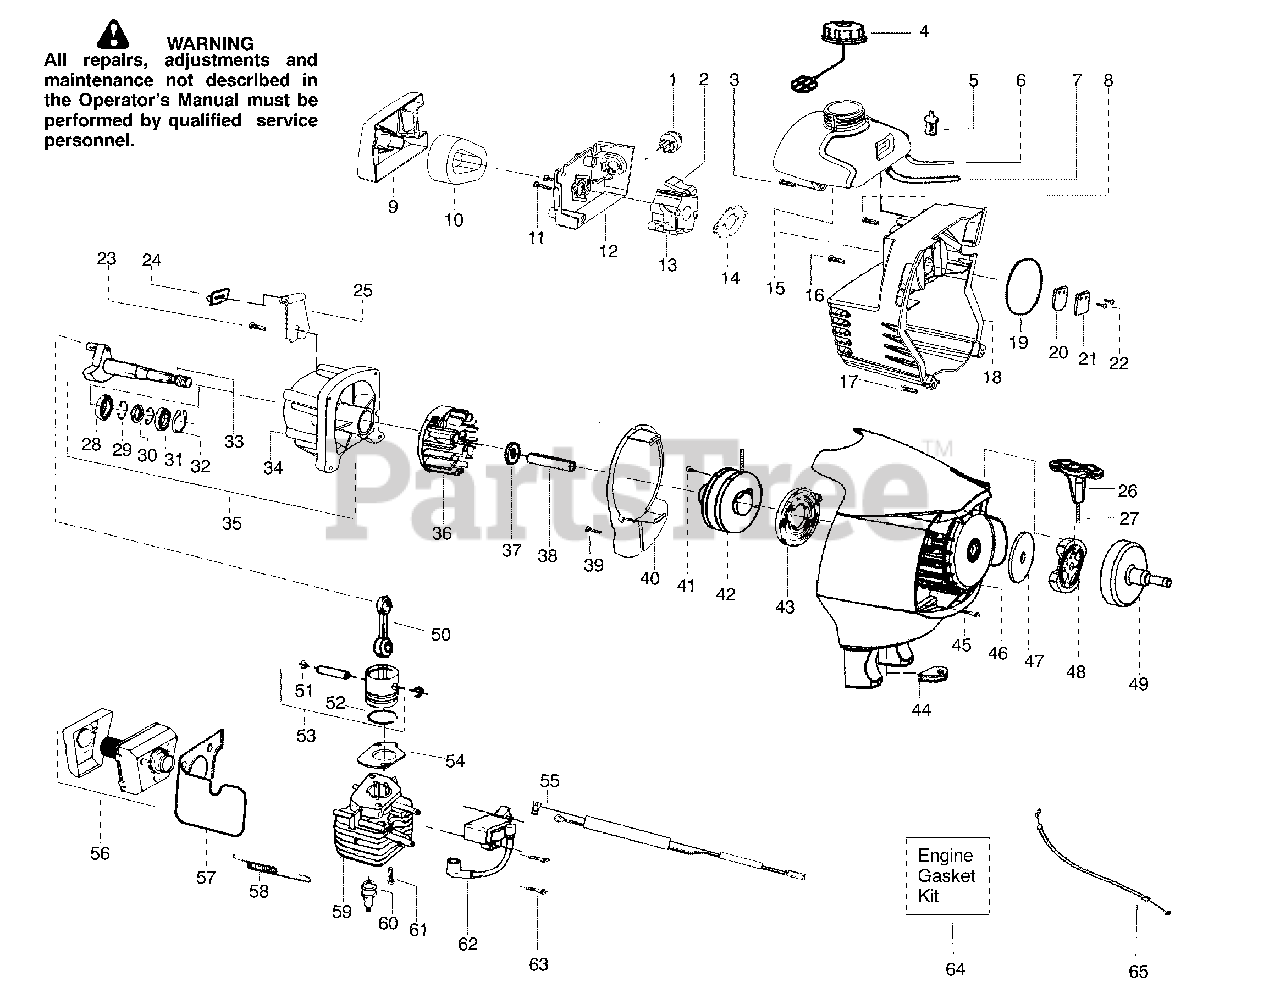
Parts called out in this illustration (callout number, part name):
1	Bulb-Purge
2	Kit-Choke Lever
3	Screw-tank
4	Cap-Fuel w/ret.
5	Assy-Fuel pickup
6	Kit-Fuel line
7	Kit-Fuel/Purge line
9	Cover-Air box
10	Filter-Air
11	Screw-Carb.
13	Assy-Carb (WT628)
14	Gasket-Carb. (kit)
15	Assy-Fuel Tank
16	Screw-Crankcase
17	Screw-Shroud
19	O-ring-Shroud (kit)
20	Valve-Reed
21	Stop-Reed
22	Screw-Reed stop
23	Screw-Retainer
24	Isolator-Tank
25	Ret.-Tank
26	Handle-Starter
27	Kit-Rope
28	Bearing-Inner
29	Retainer
31	Bearing-Outer
32	Ret.-Crankshaft
33	Assy-Crankshaft
34	Assy-Crankcase
35	Assy-C'case/C'shaft
36	Assy-Flywheel
39	Screw-Baffle
40	Plate-Baffle
41	Screw-Rope
42	Kit-Pulley
43	Spring-Starter
45	Screw-F/hsg.
46	Assy.-Fan Housing
47	Washer-Clutch
48	Assy-Clutch
49	Drum-Clutch
50	Assy-Conn. Rod
51	Ret.-Piston pin
52	Ring-Piston
53	Kit-Piston
54	Gasket-Cylinder (kit)
55	Assy-Leadwire
56	Kit-Muffler
58	Spring-Muffler
59	Cylinder
60	Plug-Spark (RCJ-6Y)
61	Bolt-Cyl. 1/4-20"
62	Module-Ignition
63	Screw-Module
64	Kit-Gasket
65	Assy-Throttle cable
